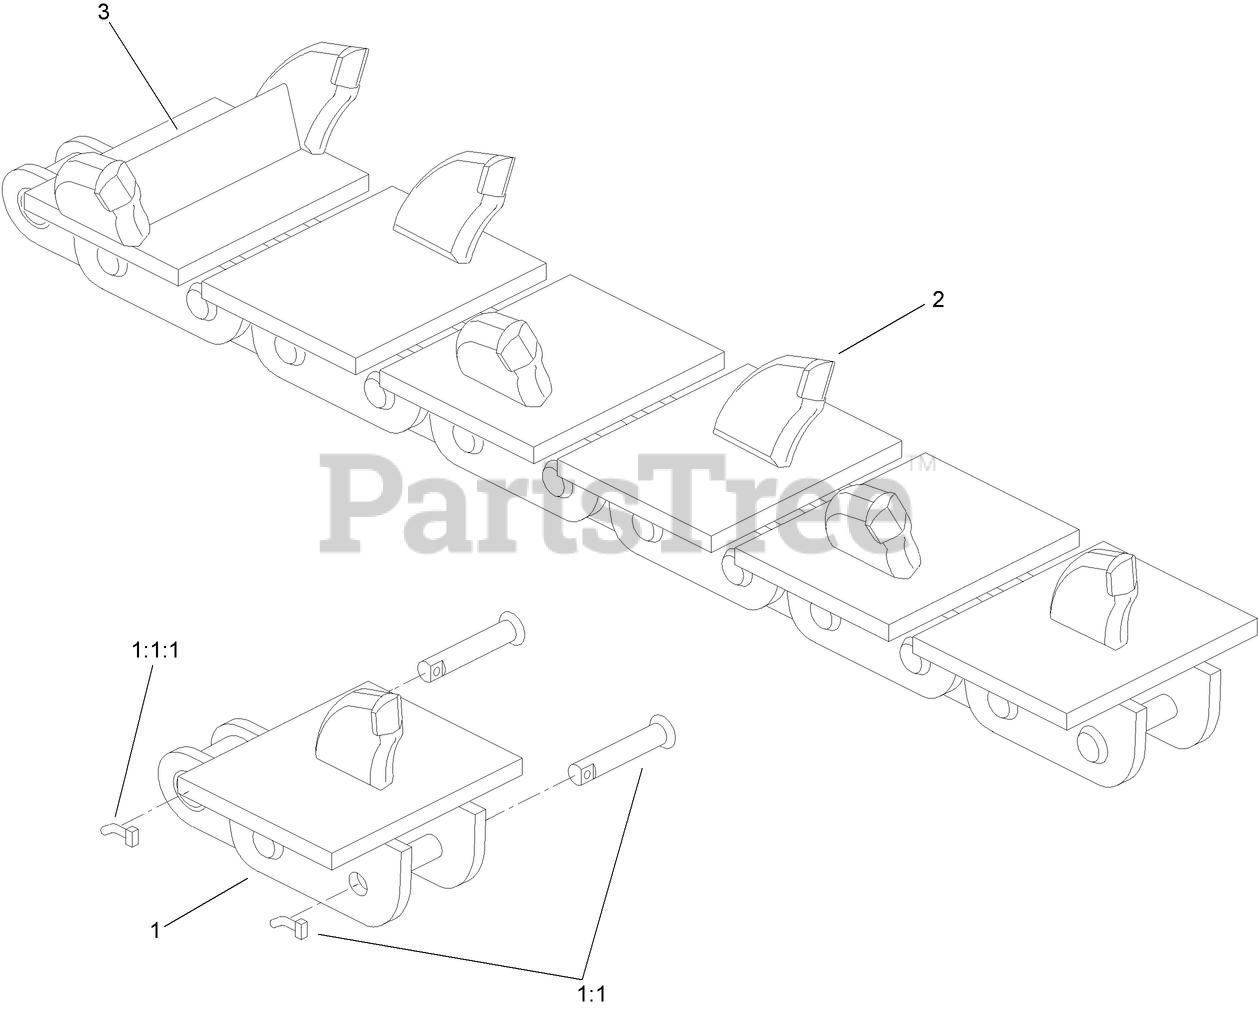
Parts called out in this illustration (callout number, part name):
1	CHAIN REPAIR LINK ASM
1:1	NOTCHED PIN AND KEEPER ASM
1:1:1	PIN-KEEPER
2	TOOTH-TERMINATOR, WELD-ON
3	DRAG-DIRT, WELD-ON (4 INCH)
